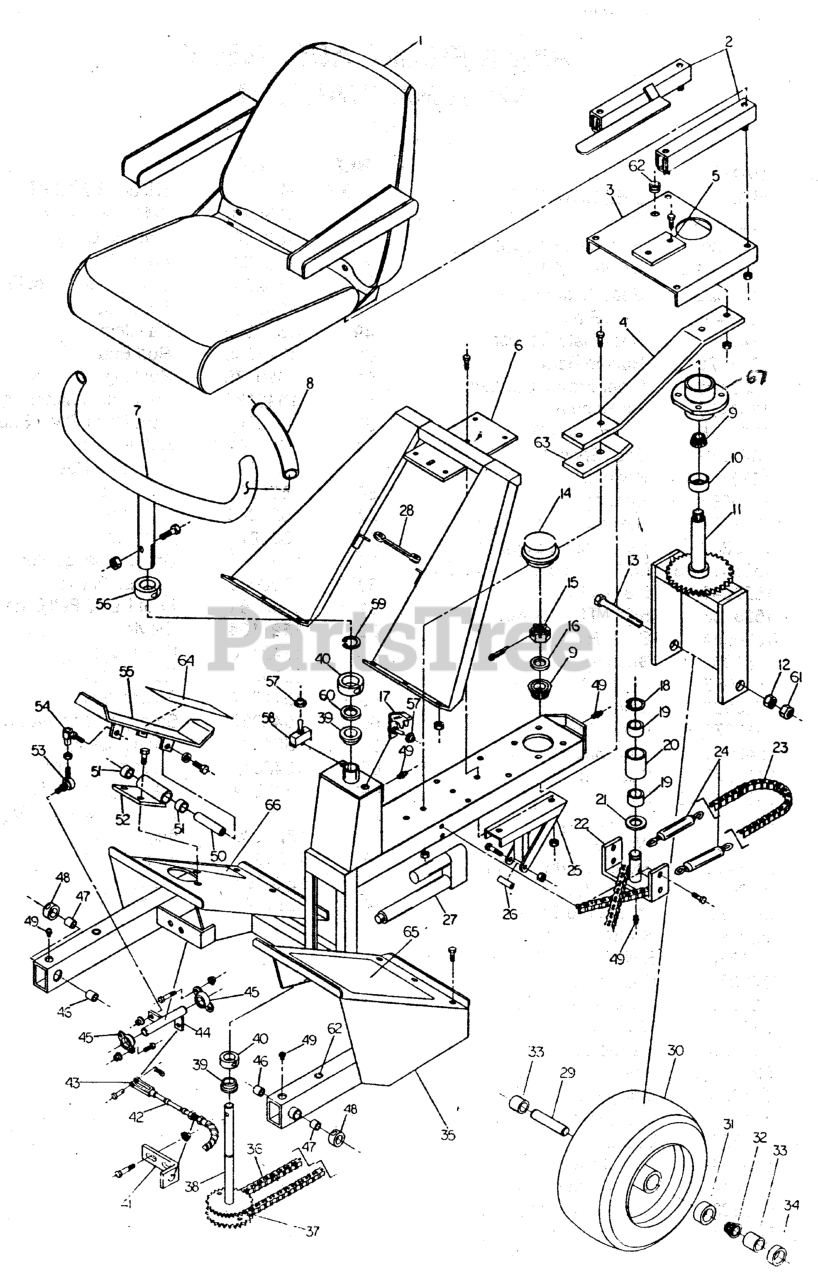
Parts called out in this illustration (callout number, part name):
1	SEAT, Black & Silver, Complete
1	ARM REST, LH
1	CUSHION, BACK
1	CUSHION, BOTTOM
1	ARM REST, RH
2	SEAT ADJUSTER RAILS (set of 2)
3	PLATE, Seat
4	SEAT SPRING
5	SUPPORT, Seat Plate
6	Rider Frame Support
7	STEERING HANDLE
8	GRIP, Foam
9	BEARING, Tapered Roller
10	SEAL, GREASE
11	MOUNT, Steering Tire
12	NUT, 5/8-11 Hex
13	BOLT, 5/8-11 x 9-1/2
14	CAP
15	NUT, 3/4-16 Hex Slotted
16	WASHER, 3/4 SAE
17	Toggle Switch
17	Switch Guard
17	SWITCH, Electric Clutch
18	SNAP RING, External
19	BUSHING, Brass
20	CHAIN ROLLER
22	Chain Roller Mount
23	CHAIN, #40 Roller, 36 Links
24	TURNBUCKLE
25	Actuator Mount
26	Actuator Spacer
27	Electric Actuator
27	ELECTRIC ACTUATOR
28	RUBBER STRAP
29	STEERING TIRE AXLE
30	WHEEL & TIRE ASSEMBLY, 18 x 7.5 x 8, White, Complete
31	BEARING CUP
32	BEARING, Tapered Roller
33	SPACER, 1.01 X 1.25 X 2.06
34	GREASE SEAL
35	Rider Frame
36	CHAIN, #40 Roller, 31 Links
37	CONNECTOR, #40 Chain Link
38	SHAFT, Steering Sprocket
39	BUSHING, Flange
40	COLLAR, 1-1/4" Split
41	CABLE BRACKET
42	CABLE, Speed Control
44	BELL CRANK
45	BEARING, Flange
46	BUSHING
47	BUSHING, Brass
48	COLLAR, 3/4" Split
49	GREASE FITTING
50	SHAFT, Pedal Pivot
51	BUSHING
52	FOOT PEDAL PIVOT MOUNT, Complete
53	BALL JOINT, 3/8-24 Male, Studded
54	BALL JOINT, 3/8" Female Studded
55	FOOT CONTROL PEDAL
56	COLLAR, 1" Split
57	Toggle Boot
58	Toggle Switch
59	Snap Ring
60	SHIM
61	NUT, 5/8-11 Hex Side Lock
62	GROMMET, 1/2"
63	SUPPORT, Seat Spring
64	SAFETY WALK
65	SAFETY WALK
66	SAFETY WALK
67	HUB, Steering
